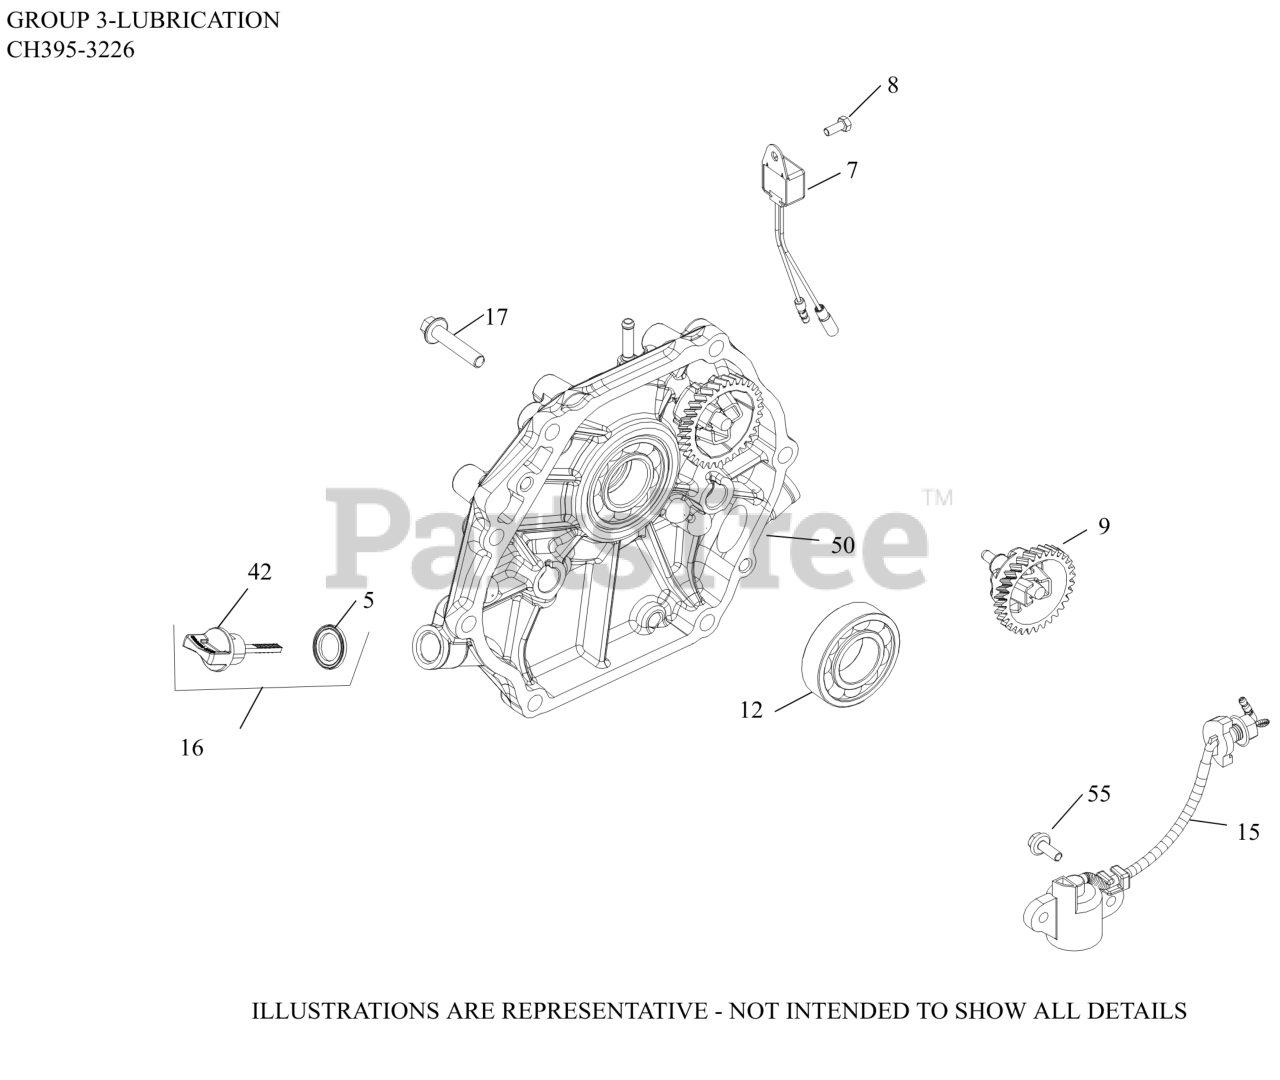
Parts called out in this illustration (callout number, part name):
5	GASKET, DIPSTICK
7	CONTROL, OIL ALERT UNIT
8	SCREW, HEX/PHILLIPS M5
9	GOVERNOR, ASSEMBLY
12	BEARING, CRANKSHAFT
15	SWITCH, OIL SENSOR ASSEMBLY
16	DIPSTICK ASSEMBLY
17	SCREW, CLOSURE PLATE
42	DIPSTICK - USE 17 038 08-S
50	PLATE, CLOSURE & BEARING
55	SCREW, M6 X 16
